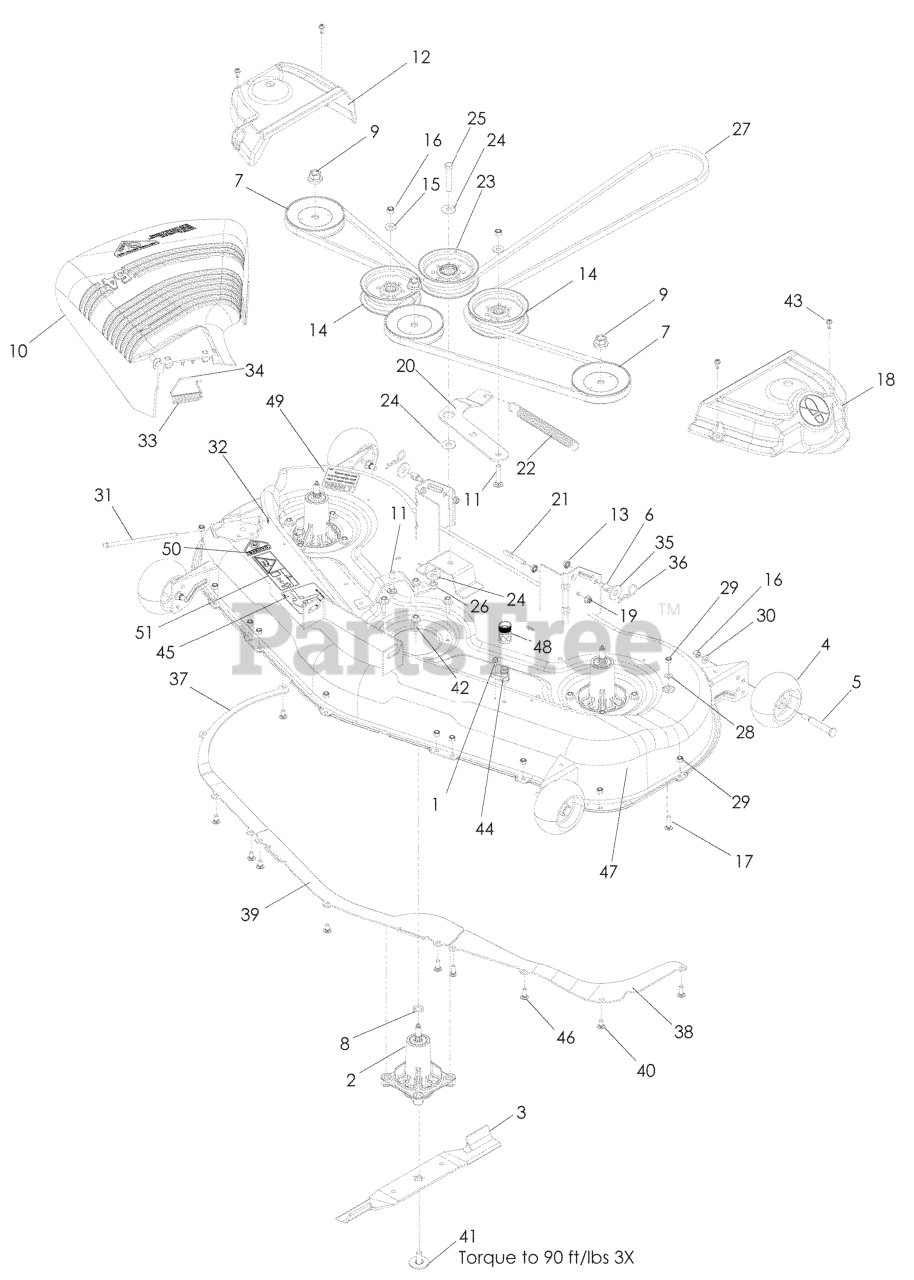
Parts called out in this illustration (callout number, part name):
1	BOLT 1/4-20 X 1/2 HWST
2	MANDREL GREASABLE
3	BLADE, BAGGING 54"
4	GAUGE WHEEL
5	SHOULDER BOLT 1/2X2-5/8 ZD SPE
6	STUD.FASTNER.W/ANTI-ROTATE
7	PULLEY
8	WASHER/SPACER
9	LOCKNUT - 9/16
10	DEFLECTOR, 54"
11	RHSNB 3/8C X 2
12	BELT SHIELD, RT
13	NUT 5/16C WHIZ
14	PULLEY.IDLER.2006
15	WASHER 3/8 FLAT
16	NUT 3/8-16 NYLOC
17	BOLT 5/16C X 3/4" CARRIAGE
18	BELT SHIELD, LT
19	5/16-18 NYLOC FLANGE NUT
20	ARM.IDLER.BLACK
21	EYE BOLT 5/16 X 3.50
22	SPRING, DECK BELT
23	PULLEY.IDLER.MWR.STATI.LH
24	WASHER 7/16 FLAT ZD
25	BOLT 7/16-14 X 2-1/2 GR 5 ZD
26	7/16-14 HEX NUT W/NYL RING ZD
27	BELT.DECK.52".54"
28	FLAT WASHER 5/16 SAE
29	NUT 5/16 NYLOC
30	WASHER 3/8 SAE FLAT
31	ROD, HINGE
32	PUSH NUT
33	TORSION SPRING
34	CAP-SLEEVE
35	WASH USS FLAT 1/2
36	HAIRPIN #4
37	BAFFLE, RIGHT 54"
38	BAFFLE LEFT 54
39	BAFFLE, CENTER, 54"
40	CARRIAGE BOLT 5/16C X 5/8"
41	BLADE BOLT ASSY-7/16" TB REPL
42	WASHER HEAD SCREW
43	SCREW- 1/4-20 X 5/8
44	PORT.WASHOUT
45	DECAL, BELT ROUTING
46	CARRIAGE BOLT 5/16C X 5/8"
47	DECK W/DECALS - RZ54
48	COUPLING.QUICK CONNECT
49	DECAL, CAUTION
50	DECAL, CPSC
51	DECAL, EURO SEVERING
